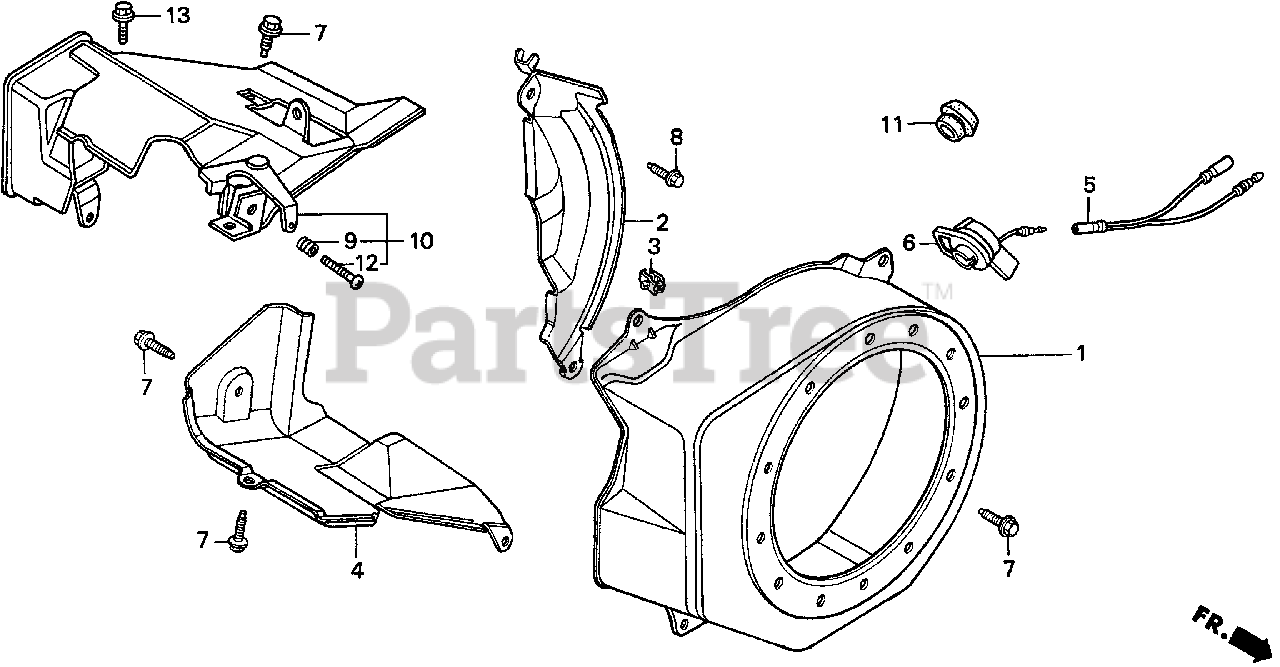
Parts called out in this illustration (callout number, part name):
1	COVER, FAN *NH1* (BLACK)
2	PLATE, SIDE (OIL ALERT)
2	PLATE, SIDE (STD)
2	PLATE, SIDE
3	CLAMP, CORD
3	CLIP, HARNESS
4	SHROUD
5	SUB-HARNESS
6	SWITCH ASSY., ENGINE STOP
7	BOLT, FLANGE (6X12) (CT200)
8	BOLT, FLANGE (6X20) (CT200)
